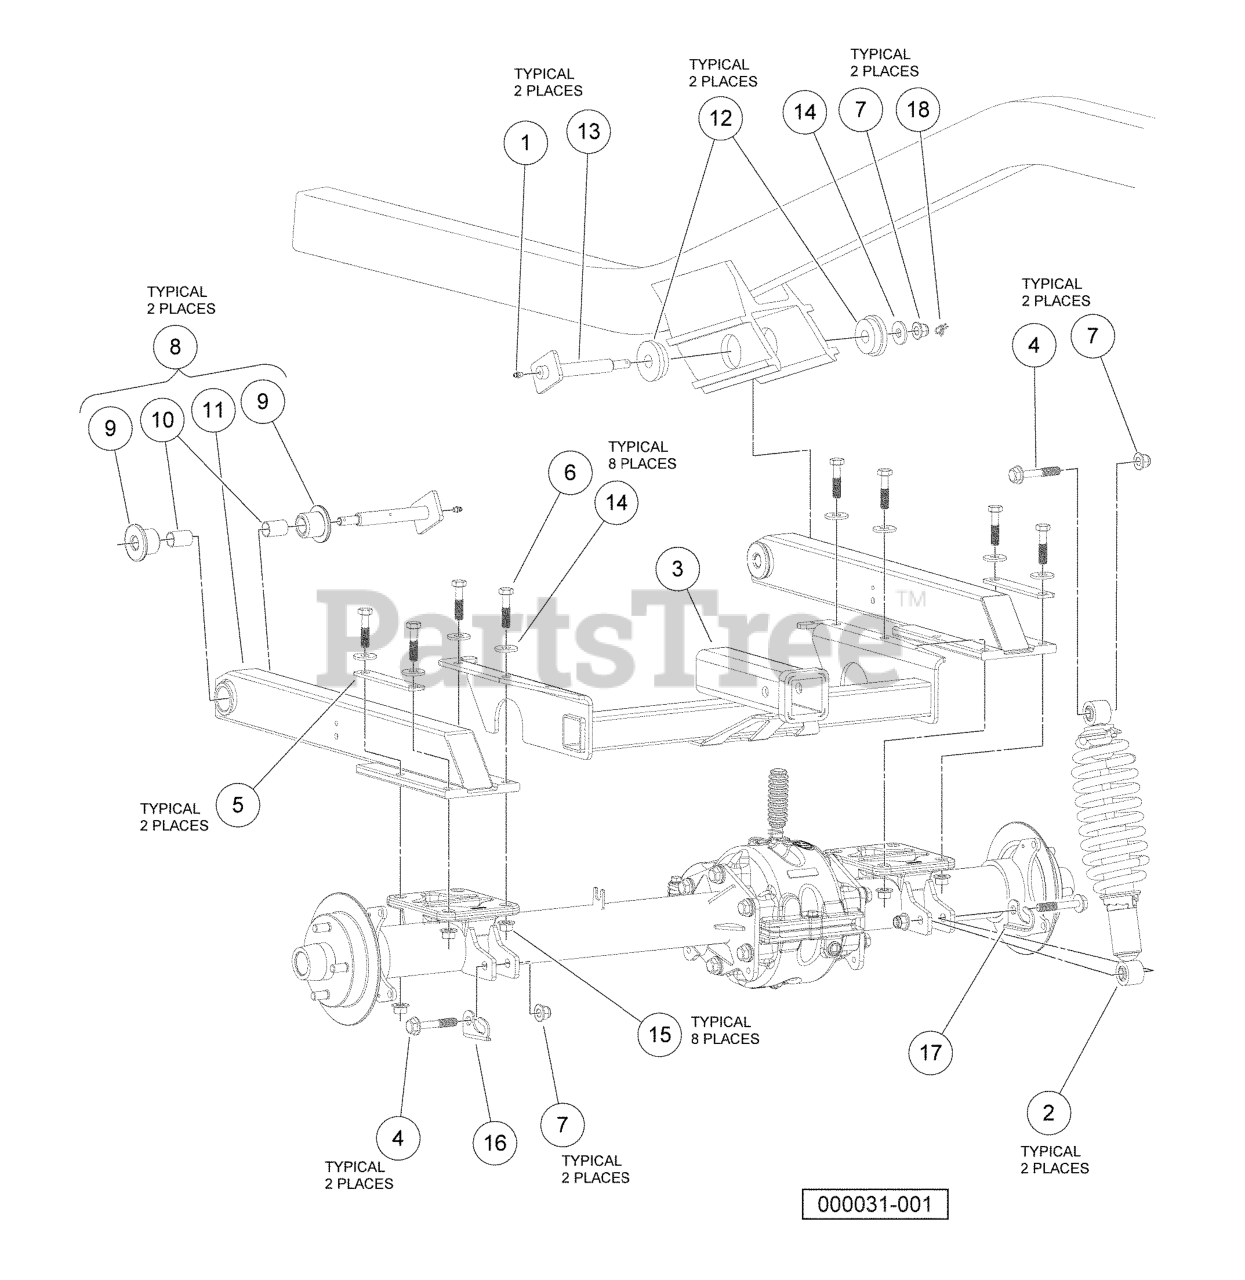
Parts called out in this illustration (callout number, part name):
1	FITTING, 1/4-28 THRD FRM GREAS
2	SHOCK, COIL OVER REAR
3	WELDMENT, RECEIVER, REAR
4	BOLT, FLG, M12X1.75X70
5	WASHER, STRIP, SWINGARM
6	BOLT FLG, M12X1.75X50
7	NUT FLG, M12X1.75, NYLON GR 10
8	Sub Asm Swingarm
9	BUSHING, PIVOT, URETHANE
10	BUSHING, TEFLON
11	SWINGARM, REAR, AWD
12	Insert, Flanged, H-Bracket
13	PIN, SWINGARM, WELDMENT
14	WASHER, M12 HARD REGULAR
16	BRKT, LINE, HYD, SHK MNT, DRV
17	BRKT, LINE, HYD, SHK MNT, PASS
18	COTTER-RUE RING
